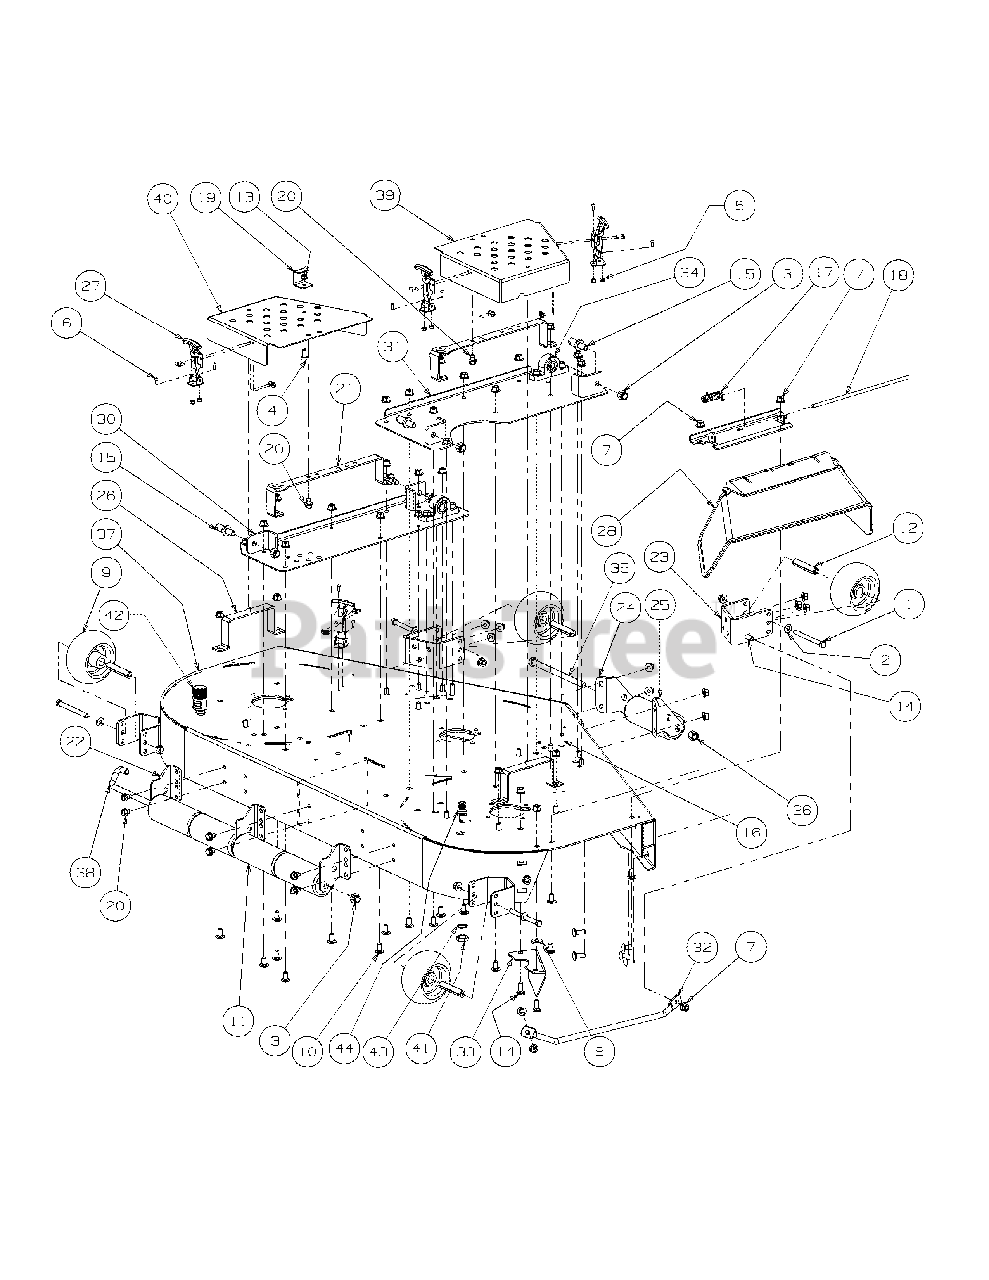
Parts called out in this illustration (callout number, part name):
1	Hex Cap Screw, 3/8-16, 3.75
2	Flat Washer, 3/8
3	Lock Nut, Nylon Insert, 1/2-13
4	Hex Cap Screw, 5/16-18 x 3/4
5	Lock Nut, Nylon Insert, 10-32
6	Phillips Head Screw, 10-32
7	Hex Nut, 3/8-16 Flange Lock
8	Idler Washer
9	Complete Wheel, 5.00 Dia.
10	Carriage Bolt, 3/8-16 x .75 Lg.
11	Front Roller
12	Wheel Spacer
13	Hexflange Lock Nut, 5/16-18
14	Carriage Bolt, 3/8-16 x 1
15	Pin, 5/8 Dia. x 1.2 Lg.
16	Carriage Screw, 3/8-16 x 1.25
17	Spring Torsion, 0.4 ID x 2.16 LG
18	Defllector Chute Rod
19	Tension Rod Stop Bracket
20	Hex Index Washer Screw, 3/8-16, .5
21	Cover Support
22	Roller Mount Bracket
23	Anti-Scalp Wheel, Front Mount Bracket
26	Outer Belt Cover Support Assembly
27	T-Handle Draw Latch
28	Deflector Chute
29	Deflector Chute Bracket
30	Left Hand Mount, Deck Bracket Assembly
31	Deck Bracket Assembly
32	Finger Guard
33	Chute Bracket
34	Pillow Block
35	Hex Cap Screw, 1/2-20 x 7.50
36	Lock Nut, Nylon Insert, 1/2-20
37	54 Deck Assembly
38	J-Hook w/ Threaded Roller
39	Right Hand Belt Deck Cover
40	Left Hand Belt Deck Cover
41	Hex Nut, M16-1.5
42	Water Nozzle Adaptor
43	Lock Washer, 17 x 23.8 x 1.95
44	Deck Water Nozzle
